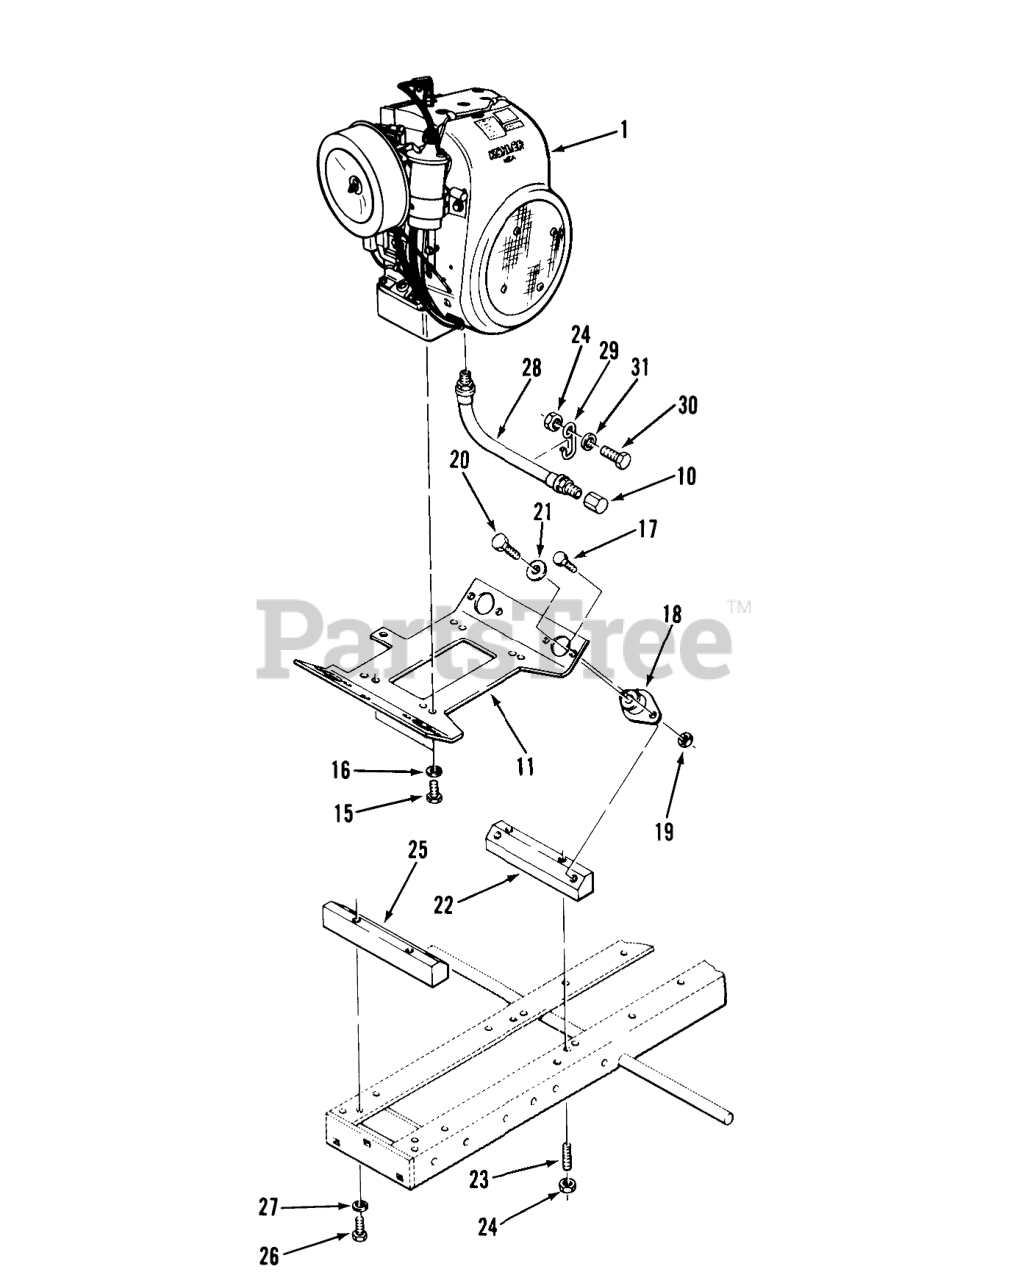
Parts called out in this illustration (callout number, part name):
1	Engine-10 HP Kohler K-241AS Spec 46812
1	Engine-12 HP Kohler K-301AS Spec 47742
1	Engine-16 HP Kohler K-341AS Spec 71311
1	Engine-14 HP Kohler K-321AS Spec 60373
10	CAP 1/4 PIPE
11	Engine Cradle
15	Bolt
16	LOCKWASHER
17	H H C S
18	MOUNT-ISOLATION
19	Nut
20	Bolt
21	Washer
22	MOUNT-BLOCK-REAR
23	SET SRW 3/8X16-1 3/4
24	Nut
25	Engine Mounting Block-Front
26	BOLT
27	LOCKWASHER
28	ASM-HOSE
29	RETAINER-HOSE
30	Bolt
31	Washer
